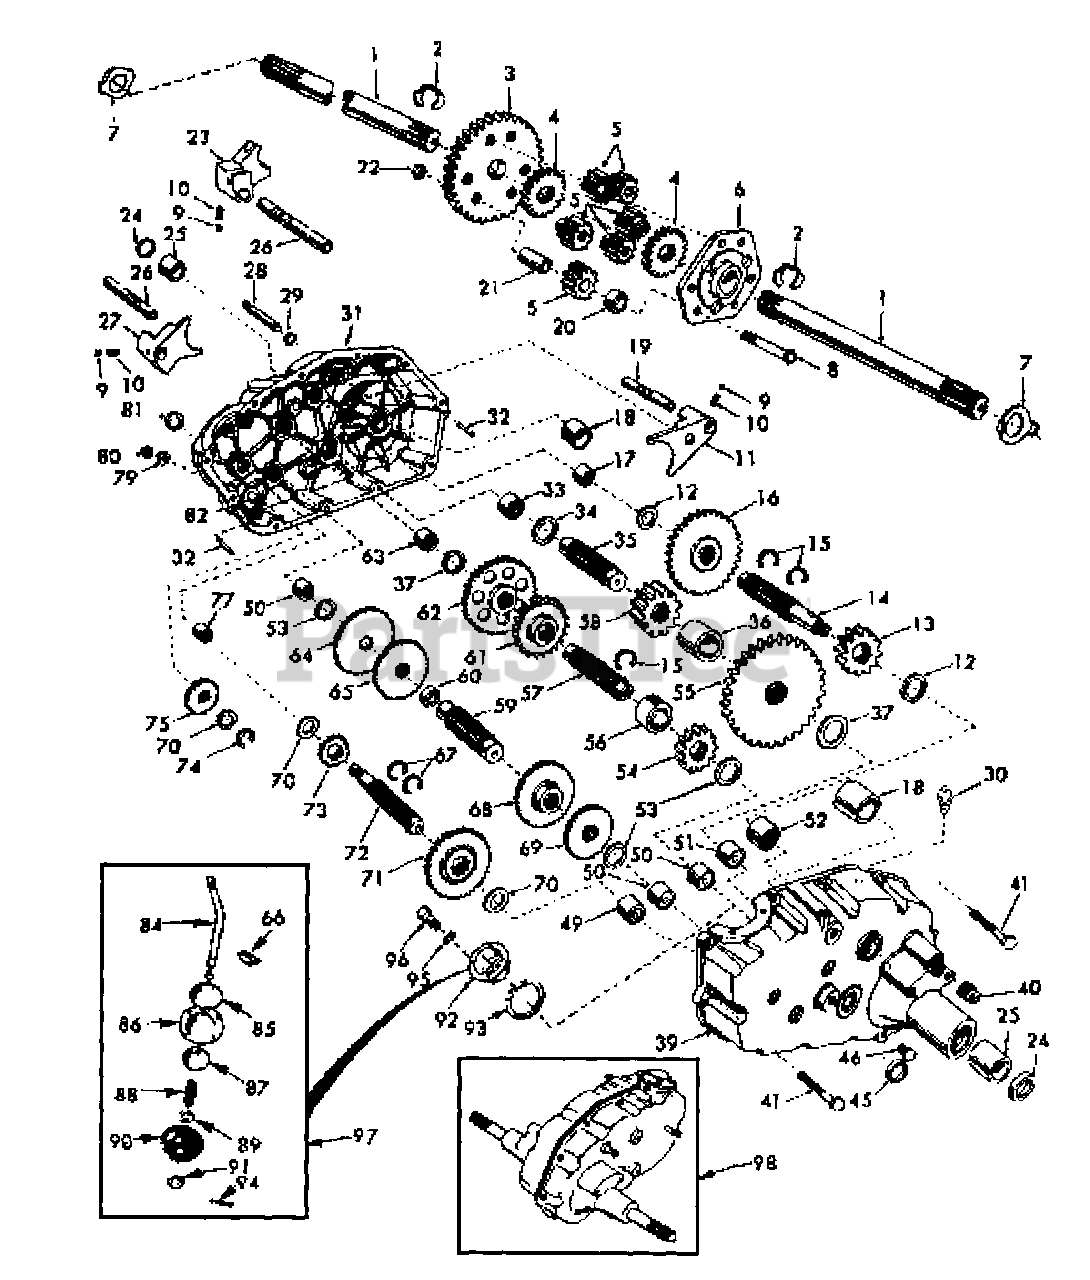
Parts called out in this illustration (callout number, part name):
1	Axle Shaft
2	Retaining Ring
3	Final Drive Gear
4	Differential Gear
5	Differential Pinion
6	Differential Carrier
7	Axle Thrust Washer
8	Bolt, Hex Head 3/8-24 x 3-1/4 (1" Thread Length)
9	Steel Ball
10	Spring Shift Fork Detent
11	Shift Fork, High-Low Range
12	Thrust Bearing Race
13	4th Reduction Pinion
14	3rd Reduction Gear Shaft
15	Snap Ring, Crescent Type
16	High-Low Range Gears
17	Needle Bearing
18	Sintered Iron Bearing
19	Shift Fork Shaft, High-Low Range
20	Differential Pinion Spacer
21	Differential Pinion Bushing
22	Gripco Centerlock Nut 3/8-24
23	Shift Fork, R.H.
24	Oil Seal
25	Sintered iron Bearing
26	Shift Fork Shaft
27	Shift Fork, L.H.
28	Shift Shaft, High-Low Range
30	Pressure Relief Valve
31	Gearcase, Reverse Idler Shaft and Bearings, R.H.
33	Needle Bearing
34	Thrust Bearing Race
35	4th Reduction Gear Shaft
36	4th Reduction Gear Spacer
37	Thrust Bearing Race
39	Gearcase and Bearings, L.H.
40	Pipe Plug 1/2-14 N.P.T.
41	Bolt, Hex 5/16-18 UNC x 1-1/4
46	Pipe Plug 1/4-18 N.P.T.
49	Needle Bearing
50	Needle Bearing
51	Needle Bearing
52	Needle Bearing
53	Thrust Bearing Race
54	3rd Reduction Pinion, Low
55	4th Reduction Gear
56	3rd Reduction Pinion Spacer
57	2nd Reduction Gear Shaft
58	Final Drive Pinion
59	1st Reduction Gear Shaft
60	1st Reduction Shaft Spacer
61	3rd Reduction Pinion High
62	2nd Reduction Gear
63	Needle Bearing
64	Low Speed Gear and 2nd Reduction Pinion Cluster
65	Reverse Gear
66	Key, Hi-Pro 1/8 x 17/32
67	Snap Ring, Crescent Type
68	Intermediate Speed Gear
69	High Speed Gear
70	Thrust Bearing Race
71	Intermediate and High Speed Cluster Pinions
72	Input Shaft
73	Low Speed Pinion
75	Reverse Idler Gear
77	Needle Bearing
79	Sealing Washer
80	Nut, Hex, Jam 7/16-20
81	Oil Seal
82	Reverse Idler Shaft
84	Gearshift Lever, Bent
85	Gearshift Cap
86	Gearshift Ball Cover and Pin
87	Shift Lever Guide Ball, Keyed
89	Washer 15/32 x 15/16 x 16 Gauge
90	Shift Mechanism Seal
91	Washer 9/16x15/16x12 Gauge
92	Gearshift Gate and Reinforcement
93	Shift Ball Cover Gasket
94	Cotter Pin 1/8 x 3/4
95	Washer, Lock 5/16
96	Bolt, Hex Head 5/16-18 UNC x 7/8
97	Gear Shift Lever Assembly
98	Transaxle, 6 Speed, Complete Assembly
